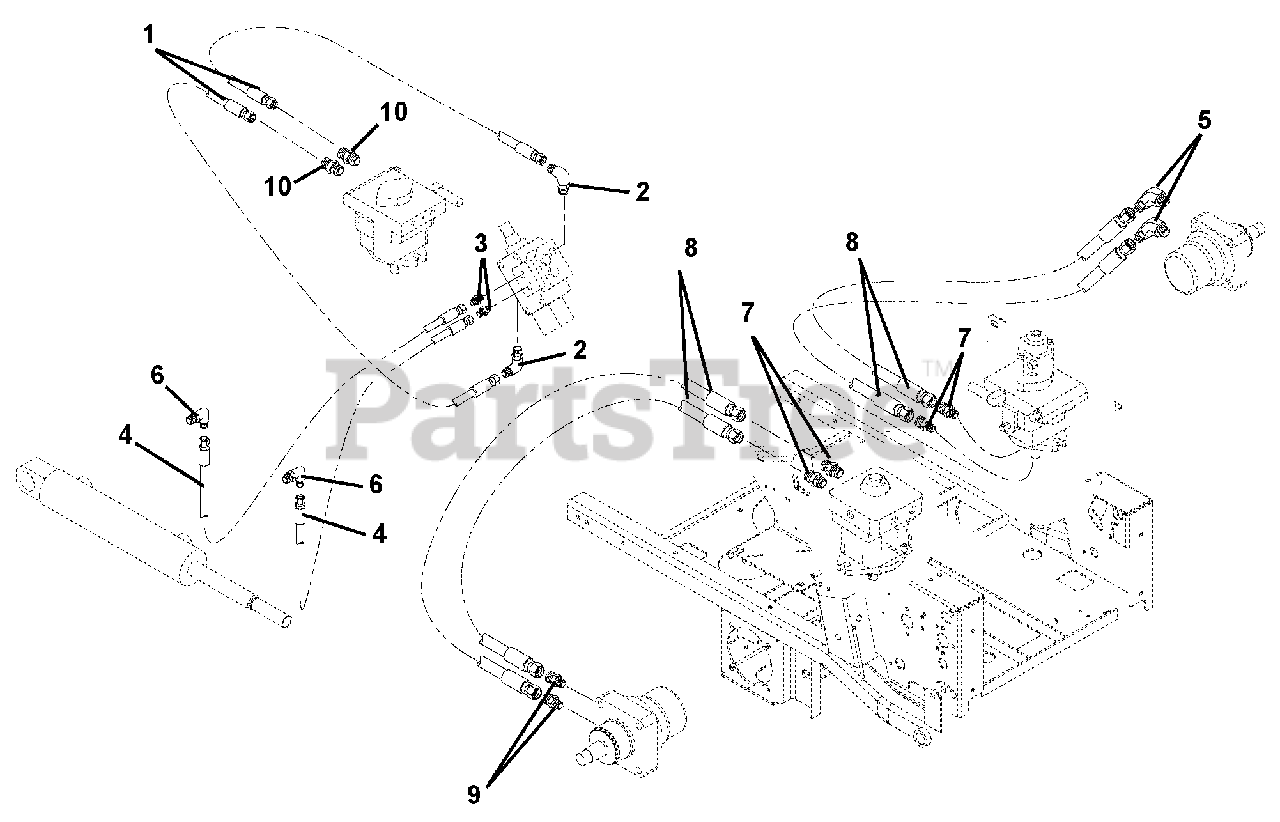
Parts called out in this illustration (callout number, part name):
1	Hose, Hydraulic (045, 046, 047, 052, 066, 067, 068, 071, 084, 085, 086, 091, 104, 106, 107, 108)
2	Hydraulic, Fitting Elbow (045, 046, 047, 052, 066, 067, 068, 071, 084, 085, 086, 091, 104, 106,
3	Adapter (4-6F5OLO) (045, 046, 047, 052, 066, 067, 068, 071, 084, 085, 086, 091, 104, 106, 107,
4	Hose, Hydraulic (045, 046, 047, 052, 066, 067, 068, 071, 084, 085, 086, 091, 104, 106, 107, 108)
5	Fitting, Hydraulic (8-10 V5OLO)
6	Fitting, Hydraulic (4 C5OLO) (045, 046, 047, 052, 066, 067, 068, 071, 084, 085, 086, 091, 104,
7	Adapter, Face Seal 8 x 8 .50 O-Ring
8	Hose, Hydraulic .50
9	Adapter, Hydraulic Steel (M10 O-M8F)
10	Fitting, Hydraulic (4 F5OLO)
